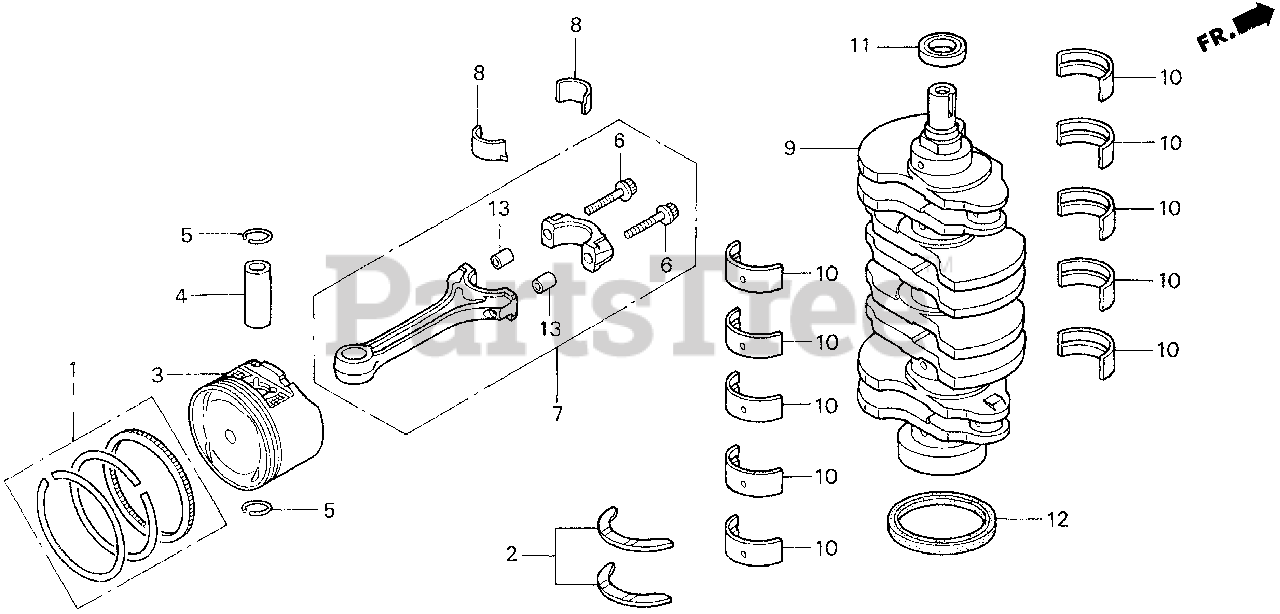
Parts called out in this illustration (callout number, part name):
1	RING SET, PISTON (STD)
2	WASHER SET, THRUST (DAIDO)
3	PISTON
4	PIN, PISTON
5	CLIP, PISTON PIN
6	BOLT, CONNECTING ROD
7	ROD, CONNECTING
8	BEARING A, CONNECTING ROD (BLUE) (GLACIER VANDERVELL)
8	BEARING B, CONNECTING ROD (BLACK) (GLACIER VANDERVELL)
8	BEARING C, CONNECTING ROD (BROWN) (GLACIER VANDERVELL)
8	BEARING D, CONNECTING ROD (GREEN) (GLACIER VANDERVELL)
8	BEARING E, CONNECTING ROD (YELLOW) (GLACIER VANDERVELL)
8	BEARING F, CONNECTING ROD (PINK) (GLACIER VANDERVELL)
8	BEARING G, CONNECTING ROD (RED) (GLACIER VANDERVELL)
9	CRANKSHAFT
10	BEARING A, MAIN (BLUE) (TAIHO)
10	BEARING B, MAIN (BLACK) (TAIHO)
10	BEARING C, MAIN (BROWN) (TAIHO)
10	BEARING D, MAIN (GREEN) (TAIHO)
10	BEARING E, MAIN (YELLOW) (TAIHO)
10	BEARING F, MAIN (PINK) (TAIHO)
11	OIL SEAL (40X52X7)
12	OIL SEAL (98X80X10) (NOK)
13	PIN, DOWEL (10X12)
